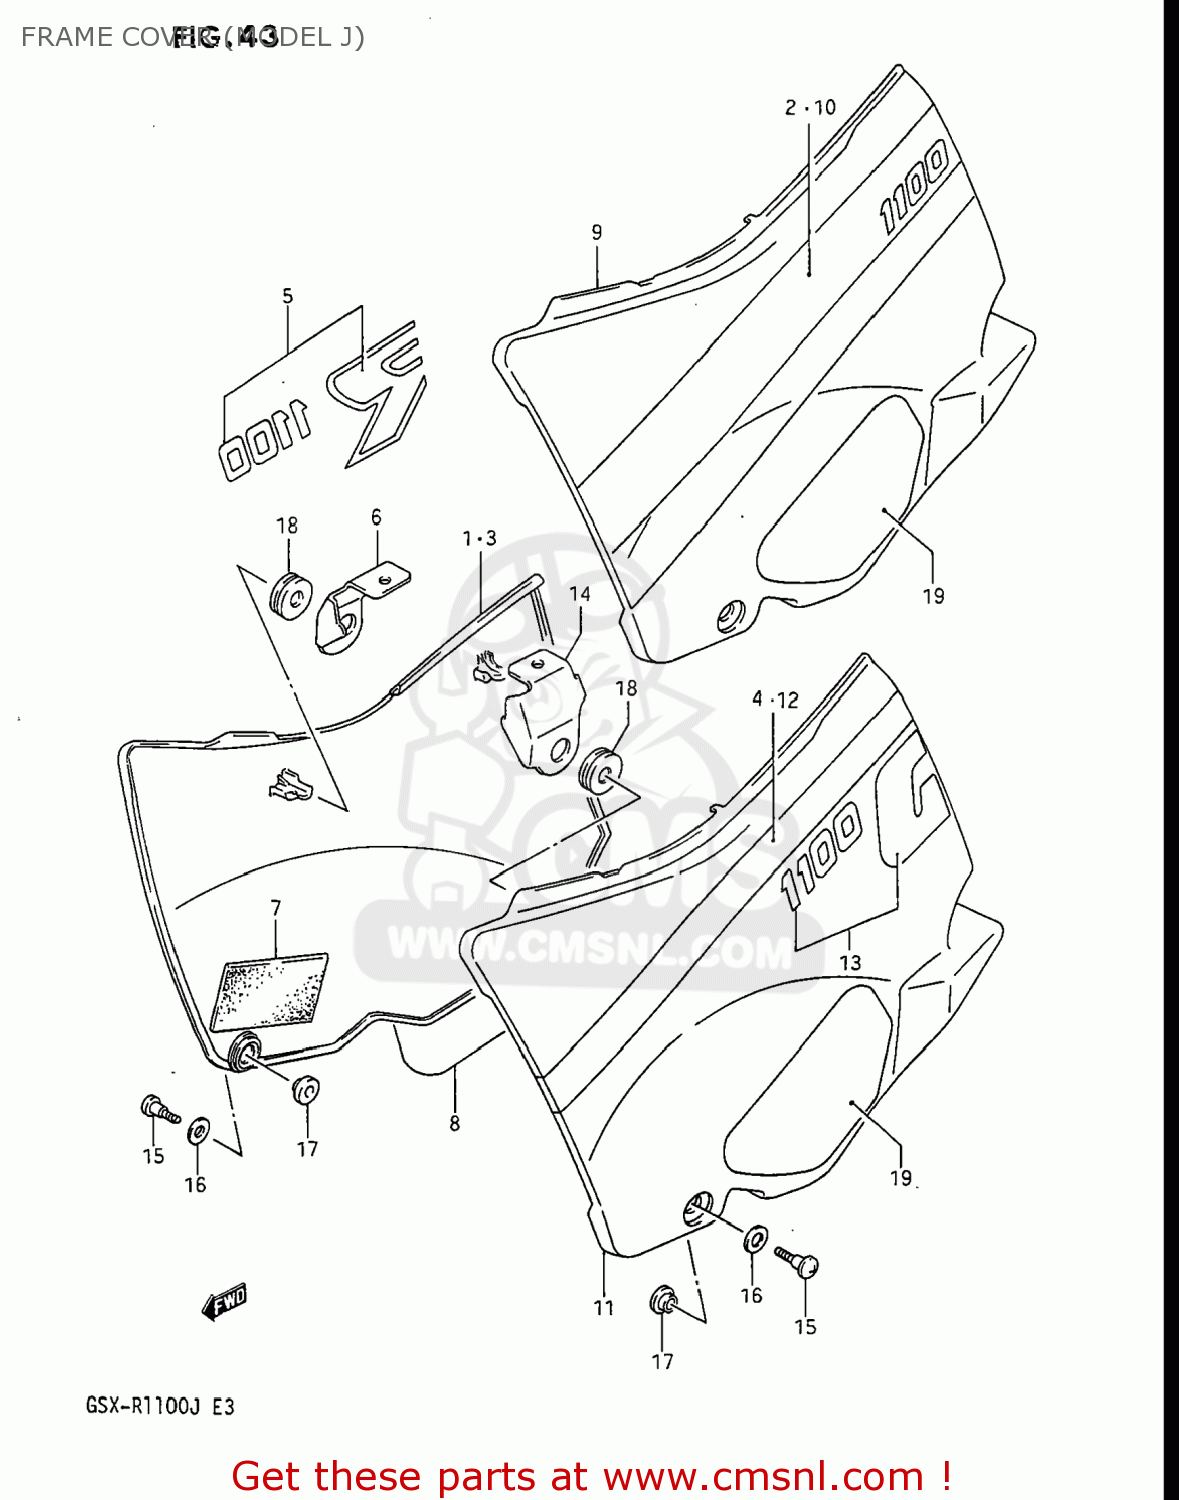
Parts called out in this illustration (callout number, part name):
1	COVER,FRAME,RIGHT
2	TAPE,FRAME COVER,RIGHT
3	COVER,FRAME,RIGHT
4	TAPE,FRAME COVER,RIGHT
5	EMBLEM,RIGHT
6	HOLDER,FRAME COVER,RIGHT
7	RUBBER,FRAME COVER,RIGHT
8	PROTECTOR,FRAME COVER
9	COVER,FRAME,LEFT
10	TAPE,FRAME COVER,LEFT
11	COVER,FRAME,LEFT
12	TAPE,FRAME COVER,LEFT
13	EMBLEM,LEFT
14	HOLDER, FRAME COVER LH
15	SCREW(6X23)
16	WASHER
17	CUSHION
18	CUSHION
19	PROTECTOR,FRAME COVER LH
